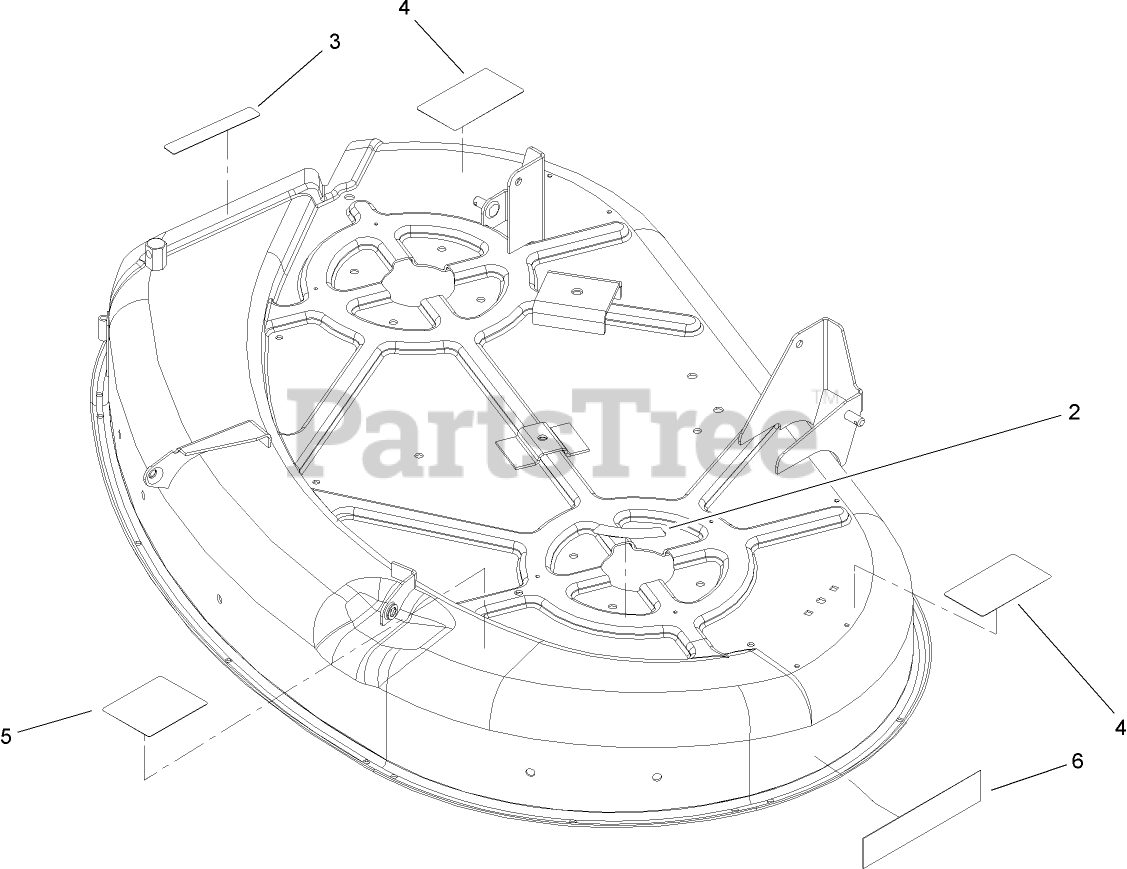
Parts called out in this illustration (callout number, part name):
2	DECAL-DANGER, SHIELD
3	DECAL-DANGER
4	DECAL-DANGER
5	DECAL-ROUTING, BELT
